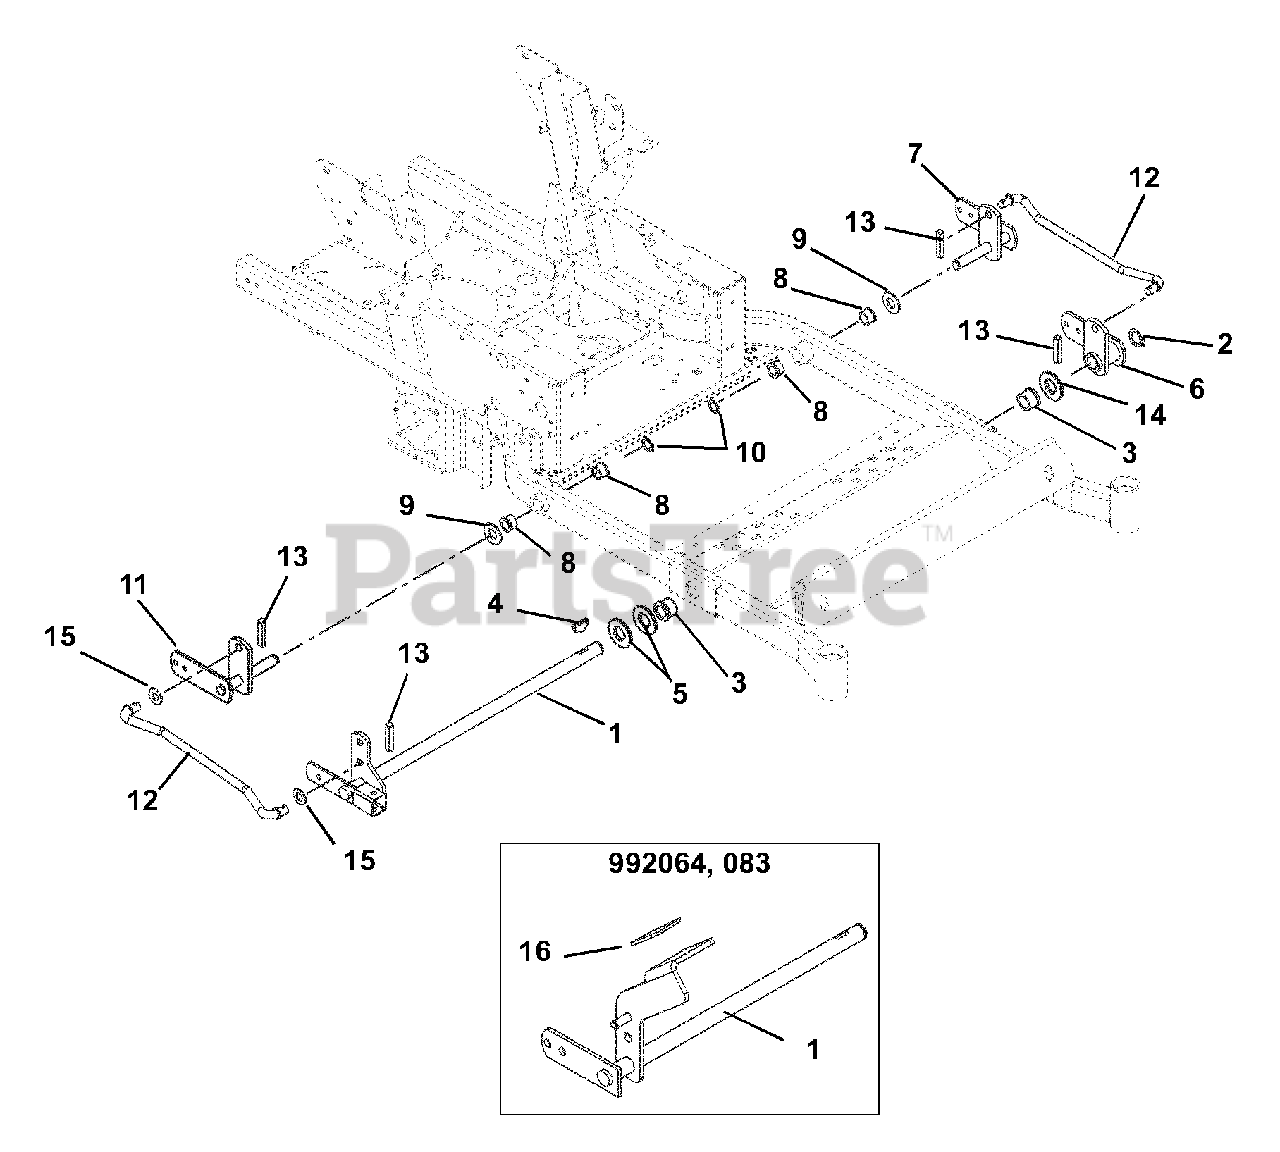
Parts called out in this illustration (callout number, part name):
1	Weldment, Lift Arm (077, 078, 079, 080, 081, 082, 310, 311)
1	Weldment, Lift Arm (064, 083)
2	Ring, Retaining External 1.00 x .078
3	Bushing, Flange Nylon 1.020 x 1.385 x .75 x 1.75
4	Key, Woodruff .25 x 1.00
5	Washer, Flat Steel 1.063 x 2.00 x .134
6	Lift Arm - Front
7	Lift Arm Shaft - Left Hand
8	Bushing, Flange Nylon .762 x 1.0 x .580 x 1.48
9	Washer, Hardened Steel .758 x 1.23 x .031
10	Ring, Retaining External .689 x .077
11	Lift Arm Shaft - Right Hand
12	Rod, Lift Assist
13	Pin, Roll .25 x 1.25
14	Washer, Hardened Thrust 1.00 x 1.55 x .03
15	Washer-Flat-Steel .656 x 1.31 x .095
16	Grip, Pedal (064, 083)
